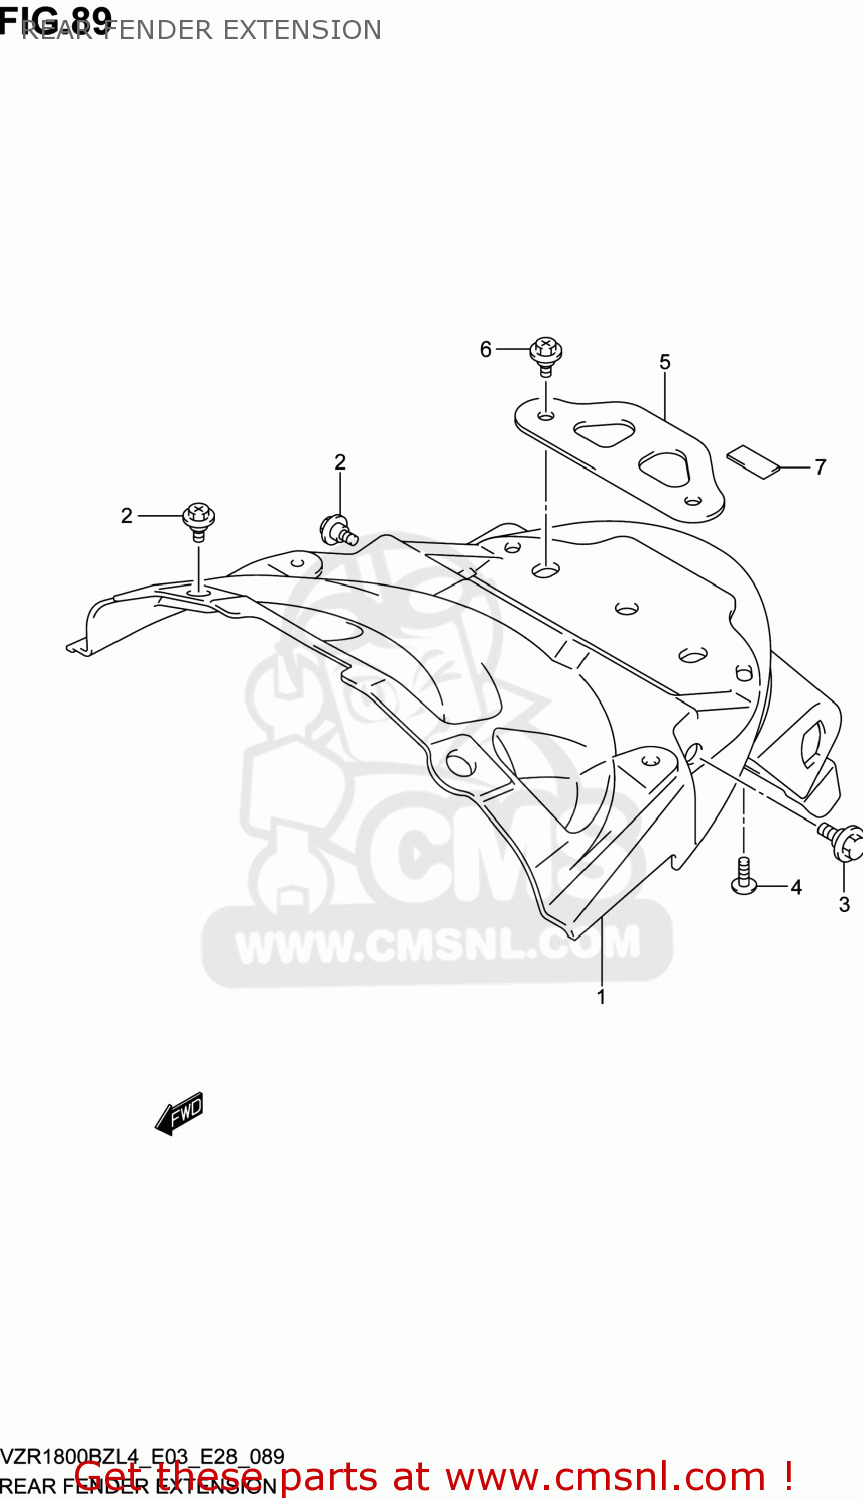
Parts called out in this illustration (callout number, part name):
1	EXTENSION,RR FENDER
2	BOLT
3	BOLT(6X16.5)
4	SCREW
5	PLATE,RR FENDER EXTENSION
6	BOLT(6X10)
7	CUSHION,RR FENDER EXT PLATE
